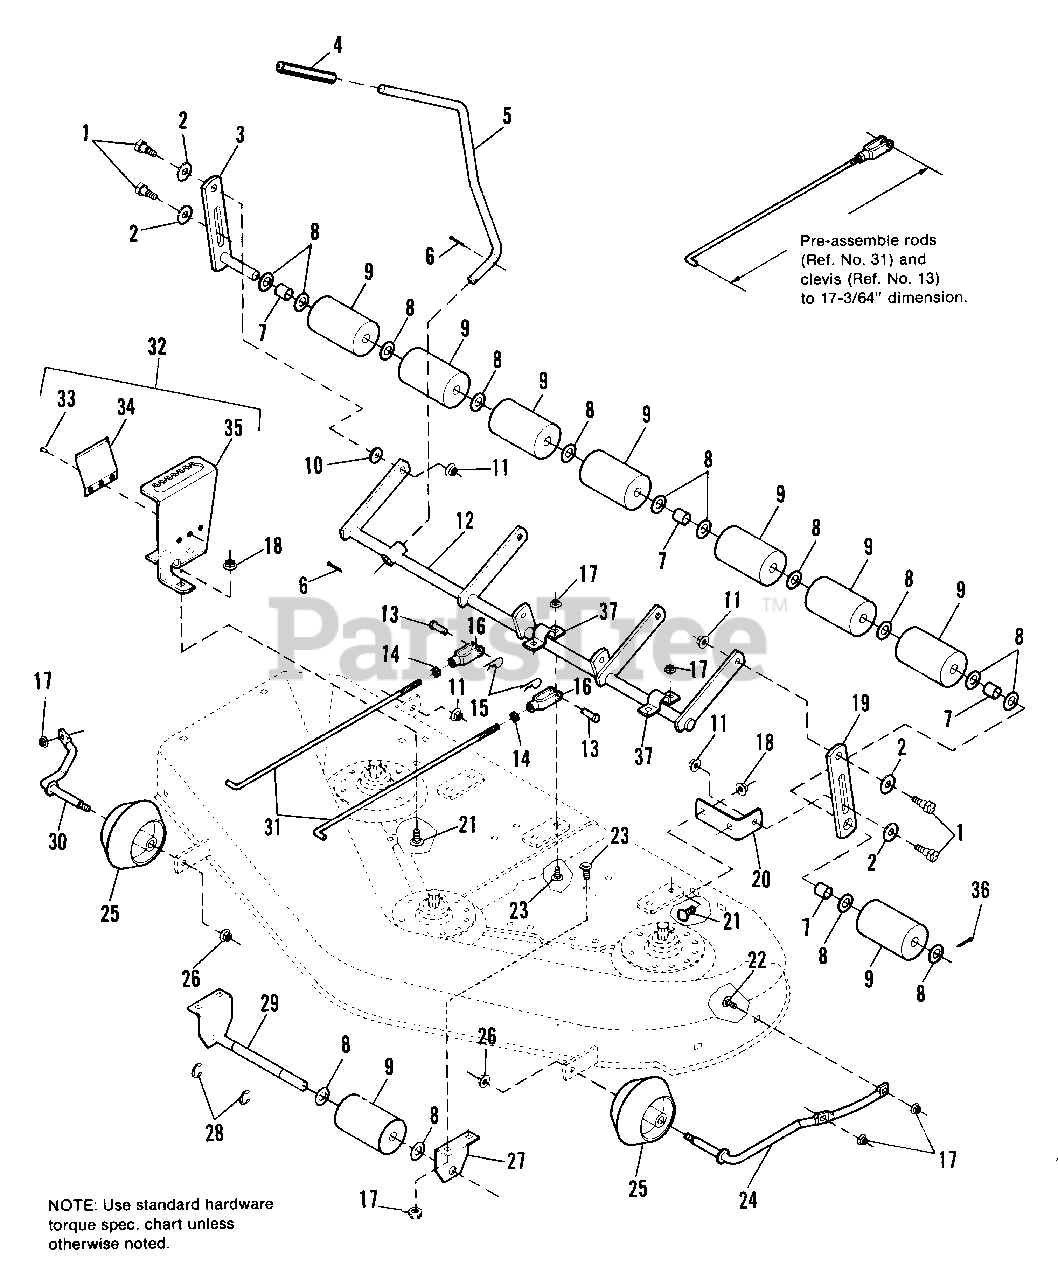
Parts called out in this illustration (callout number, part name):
1	BOLT, Shoulder, 3/8-16 X 1.34
2	WASHER, 1/2
3	SHAFT ASSY., Roller
5	LEVER, Control
6	PIN, Cotter
7	SPACER, .66 ID
8	WASHER, 5/8
10	WASHER, 3/8
11	NUT, Whizlock, 3/8-16
12	ARM ASSY., Mower
13	PIN, Clevis
14	NUT, Hex, 3/8-16
15	PIN, Quick
16	CLEVIS, Adjusting
17	NUT, Hex Whizlock, 5/16-18
18	NUT, Hex Whizlock, 3/8-16
19	BAR, Roller
20	BRACKET, Roller Support
21	CARRIAGE BOLT, 3/8-16 x 3/4
22	CARRIAGE BOLT, 5/16-18 x 5/8
23	CARRIAGE BOLT, 5/16-18 x 3/4
24	ROD ASSY., Roller, L.H.
26	NUT, Hex, Esna Lock 3/8-16
28	RING, Retaining
29	SHAFT ASSY.
30	ROD ASSY., Roller, R.H.
31	ROD, Adjusting
32	QUADRANT ASSY. (Incl. Ref. Nos. 33-35)
36	PIN, Cotter
37	STRAP
